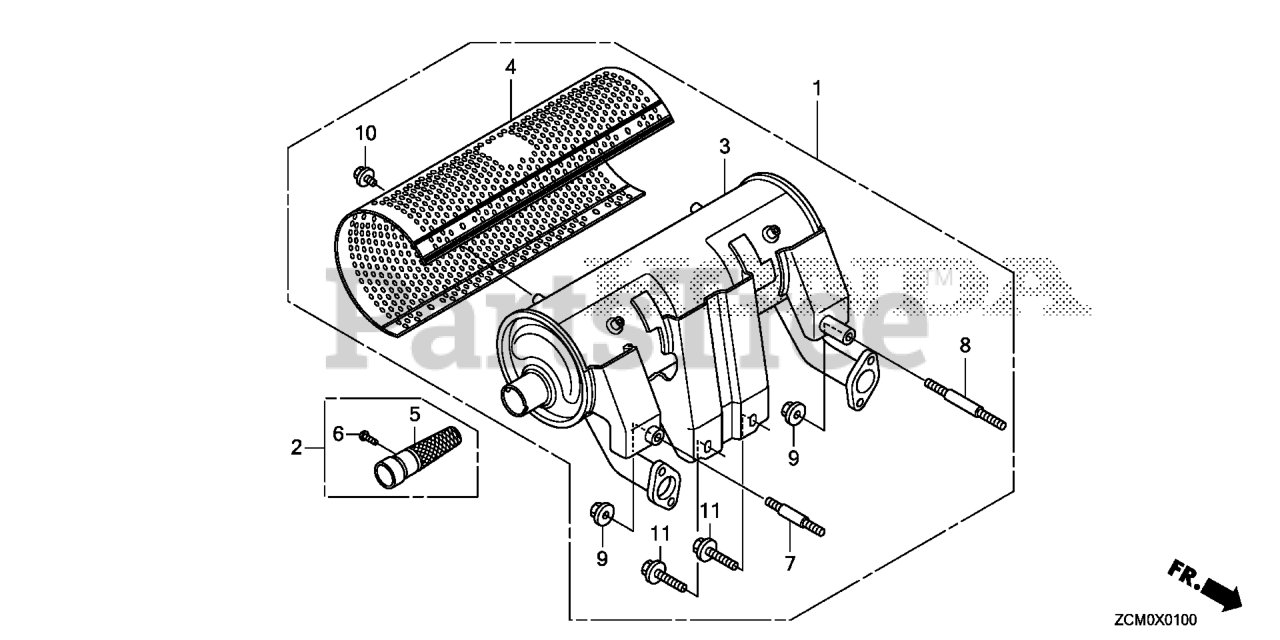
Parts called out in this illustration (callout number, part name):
1	MUFFLER KIT (HIGH-R)
2	ARRESTER KIT (HIGH)
3	MUFFLER (HIGH-R)
4	PROTECTOR, MUFFLER (HIGH) (FUTABA)
5	ARRESTER, SPARK
6	SCREW, TAPPING (5X8) (FOR SILVER MUFFLER)
7	BOLT, STUD (8X45)
8	BOLT, STUD (8X60)
9	NUT, FLANGE (8MM)
10	BOLT, FLANGE (6X8)
11	BOLT, FLANGE (8X20) Use up to Engine SN 1609606.
